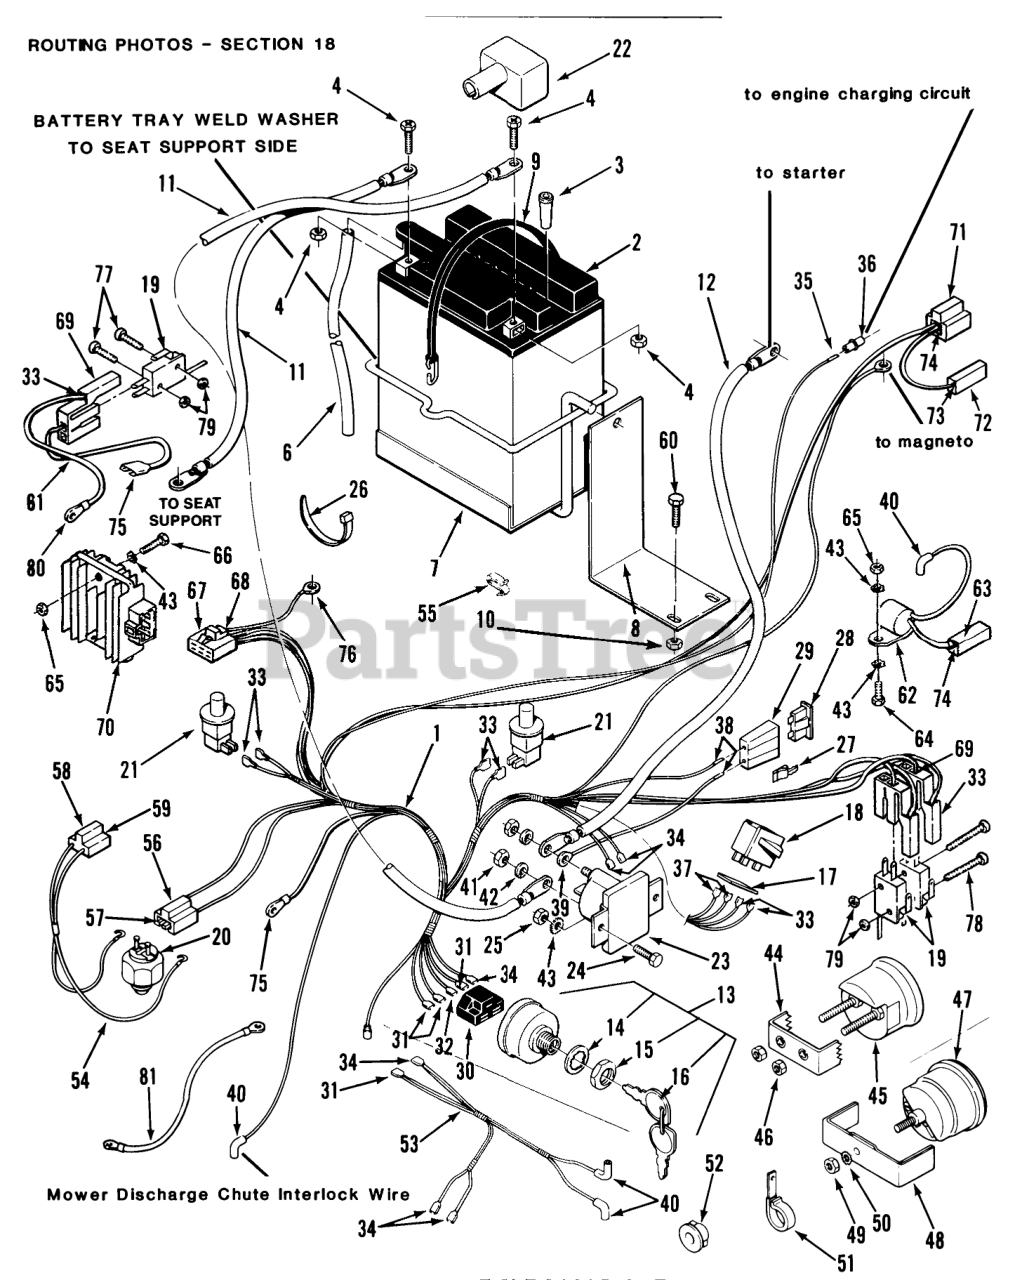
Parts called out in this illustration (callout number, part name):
1	WIRING HARNESS
2	BATTERY 120CCA
3	ADAPTER
4	ASSY BATTERY HDW
6	HOSE BATTERY DRAIN
7	BATTERY TRAY B
8	BRACKET B
9	STRAP
10	Nut
11	ASSY WIRE
12	WIRE ASM
13	Ignition Switch (includes items 14 & 15)
14	LOCKWASHER
16	Ignition Key
17	SHIELD-DIRT (DPDT)
18	PTO Interlock Switch w/item 17
19	SWITCH
20	SWITCH (N.C.-TRANS)
21	SWITCH (N.C.)
22	COVER-TERMINAL
23	Solenoid
24	Screw
25	Nut
26	PLASTIC TIE
28	FUSE-BLADE, 15 AMP
29	AUTO-FUSEBLOCK TERM
30	CONNECTOR-5 WAY-SERV
31	Terminal
32	Wire Terminal (Part of 1)
33	Wire Terminal (Part of 1)
34	Connector .250 x .032
35	Terminal
36	SOCKET HOUSING
37	Wire Terminal (Part of 1)
38	TERMINAL-FUSE
39	Wire Terminal (Part of 1)
40	Terminal Part of 5
41	Nut
42	Washer
43	LOCKWASHER
44	CLAMP MOUNTING
45	Voltmeter (includes items 44 & 46) 108-5 111-6, 112-C
46	HEX NUT 10-32 E.S.
47	Hourmeter (includes items 48, 49 50 & 51) 111-6 & 112-C
48	HOUR METER CLAMP
49	Hex Nut
50	Lockwasher
51	CLAMP
52	BUSHING-NYLON .75
53	Volt & Hourmeter Harness
54	ASSY WIRING HARNESS
55	SPEED CLIP
56	CONNECTOR BODY
57	Male Terminals (Part of 1)
58	CONNECTOR BODY B
59	TERMINAL-TAB RCPT
60	Bolt
61	WIRING-HARNESS
62	Interlock Module 112-C Only
63	CONNECTOR BODY ELECT
64	Screw
65	Nut
66	HHCS 1/4-20X1" WHIZ
67	CONNECTOR BODY
68	Terminal 212 (part of item 2)
69	CONNECTOR BODY
70	REGULATOR VOLTAGE
71	3-CONTACT LOCK-TYPE
72	CONNECTOR-5 WAY-SERV
73	Male Terminals (Part of 1)
74	TERMINAL-LONG MALE
75	Wire Terminal (Part of 1)
76	Ring Terminal 1/4 (Part of 1)
77	Screw
78	Screw
79	NUT HEX 4-40 ELAST
80	Piggy-Back Connector(Part of 6)
81	WIRE-BONDING
